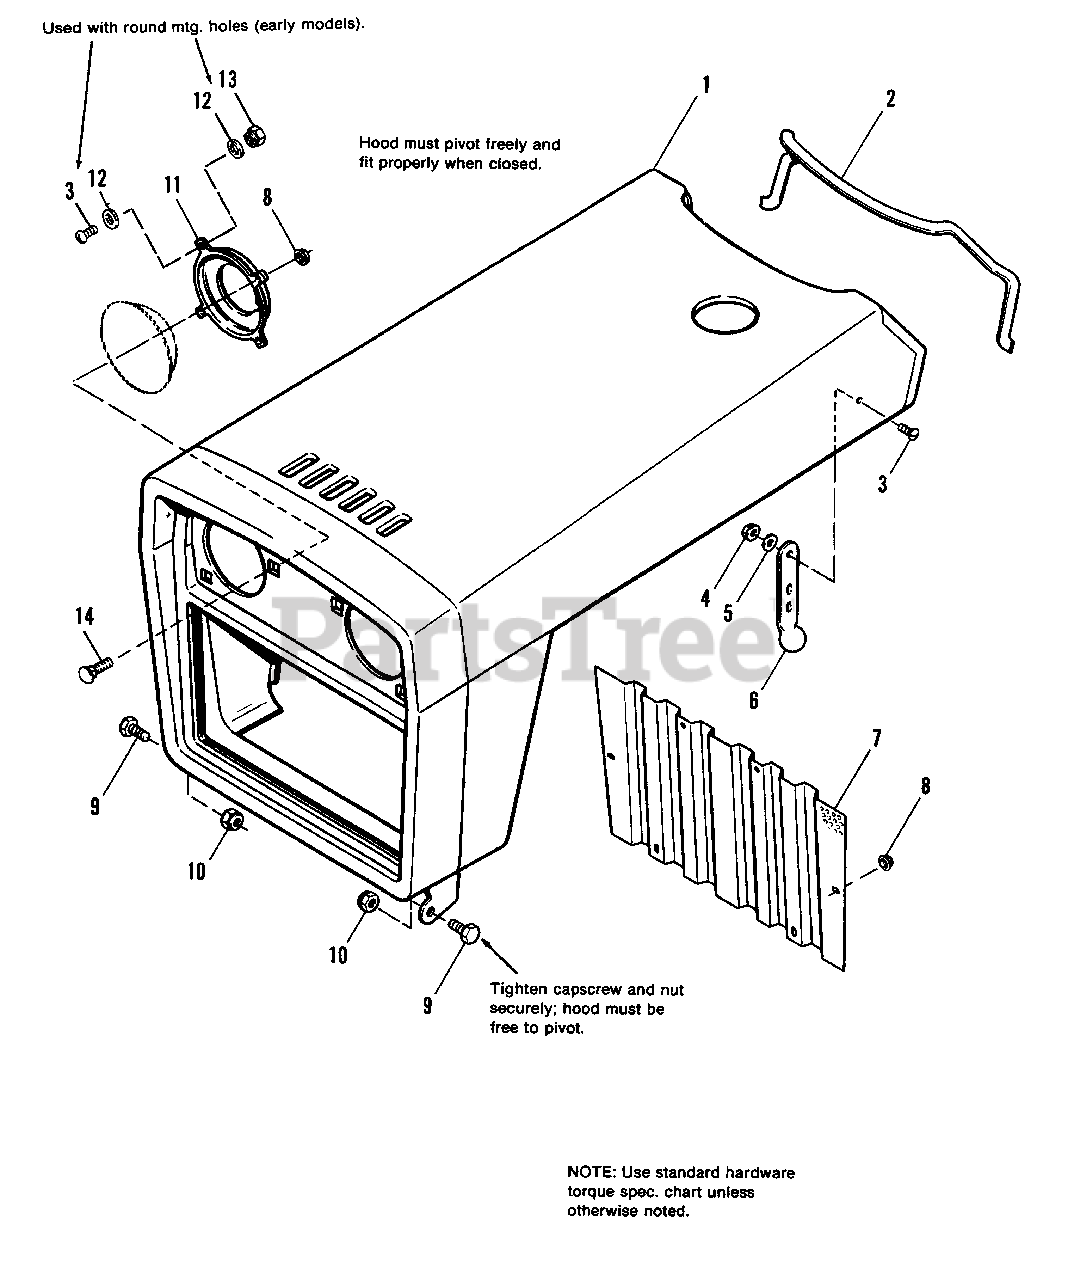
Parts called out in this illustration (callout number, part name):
1	HOOD & GRILLE ASSY.
2	MOULDING, Hood
3	SCREW, Truss Hd., #10-32 x 1/2 (Qty. 2 used on early models)
4	LOCKNUT, Hex, #10-32
5	WASHER, Special
6	STRAP, Hood
8	LOCKNUT, Pal (Qty.10 used on later models)
9	CAPSCREW, Hex Hd., 3/8-16 x 1
10	LOCKNUT, Hex, 3/8-16
11	BRACKET, Headlight
12	WASHER, Flat, 3/16
13	NUT & WASHER, #10-32
14	BOLT, Carriage, #10-29 x 1/2
